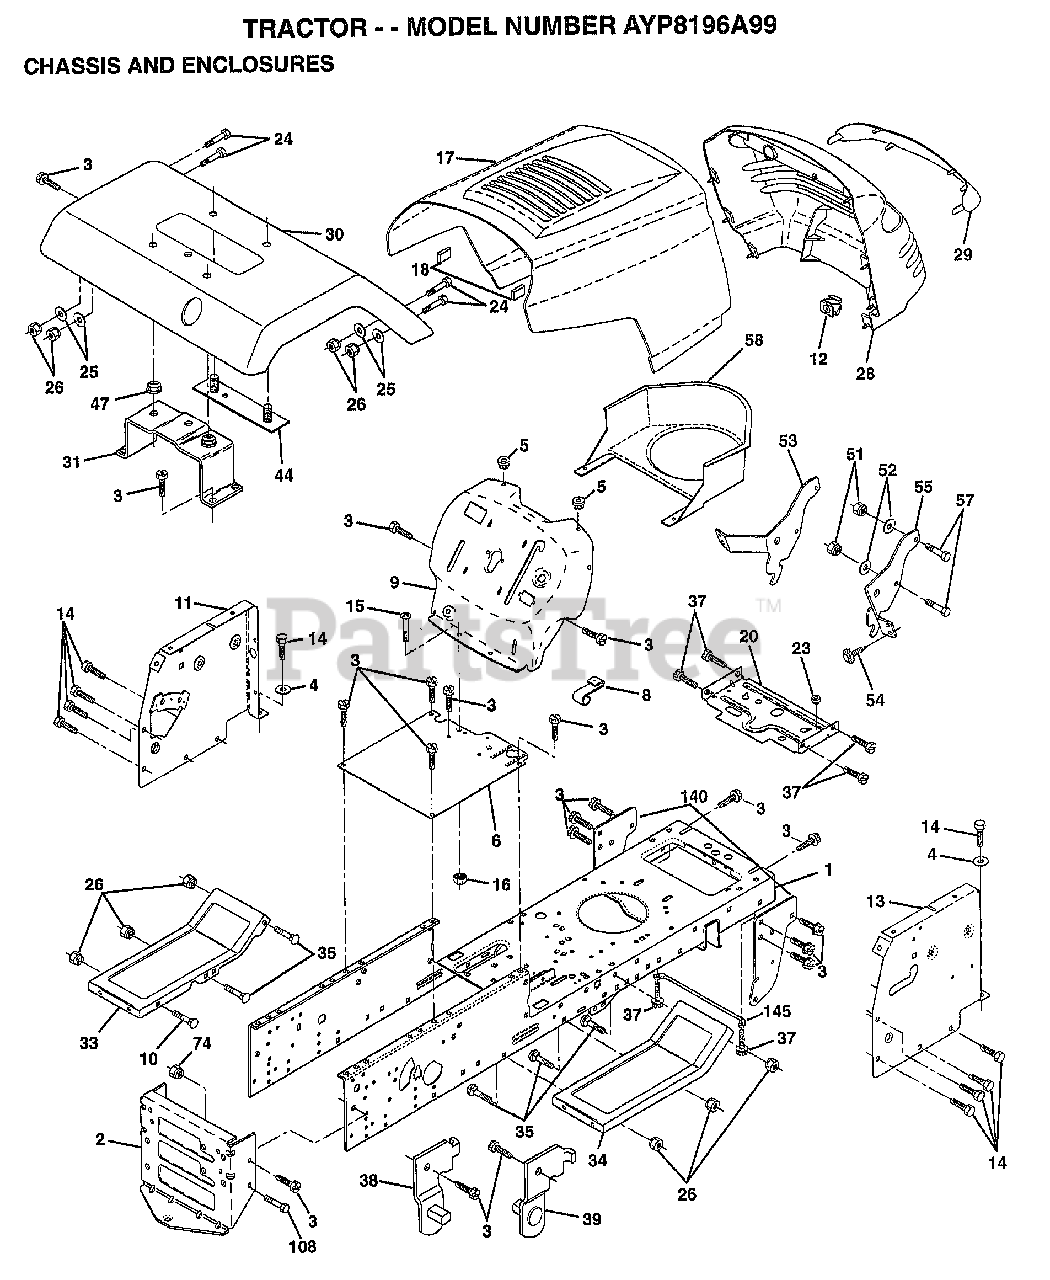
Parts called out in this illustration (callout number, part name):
1	CHASSIS.STAMPING
3	SCREW
4	WASHER
5	BUMPER-HOOD/DASH
6	SADDLE
8	"CLIP,INSULATOR"
9	DASH.SILKSCREEN
11	PANEL ASM DASH LH
12	CLIP.TINNERMAN
13	PANEL DASH RH
14	SCREW LT
15	SCREW
20	"PLATE-MTG,BATT/FU"
24	BOLT
25	WASHER
26	NUT
28	GRILLE-MS428
29	LENS.GRILLE.PRIVATE LABEL
30	FENDER.PNT.
31	BRKT.ASM.FENDER
33	FOOTREST.LH.LT/GT
34	FOOTREST.RH.LT/GT
35	BOLT
37	SCREW LT
38	BRACKET ASM LH
39	BRACKET ASM RH
44	STRAP ASM FENDER
47	NUT-PUSH YT
51	NUT
52	WASHER
53	BRACKET.GRILLE.LH
54	SCREW.HEX.WS.HD
55	BRACKET.GRILLE.RH
58	DUCT.AIR.B&S.18HP
140	BRKT SUSPENSION
145	"ROD POVOT,CHASSIS"
